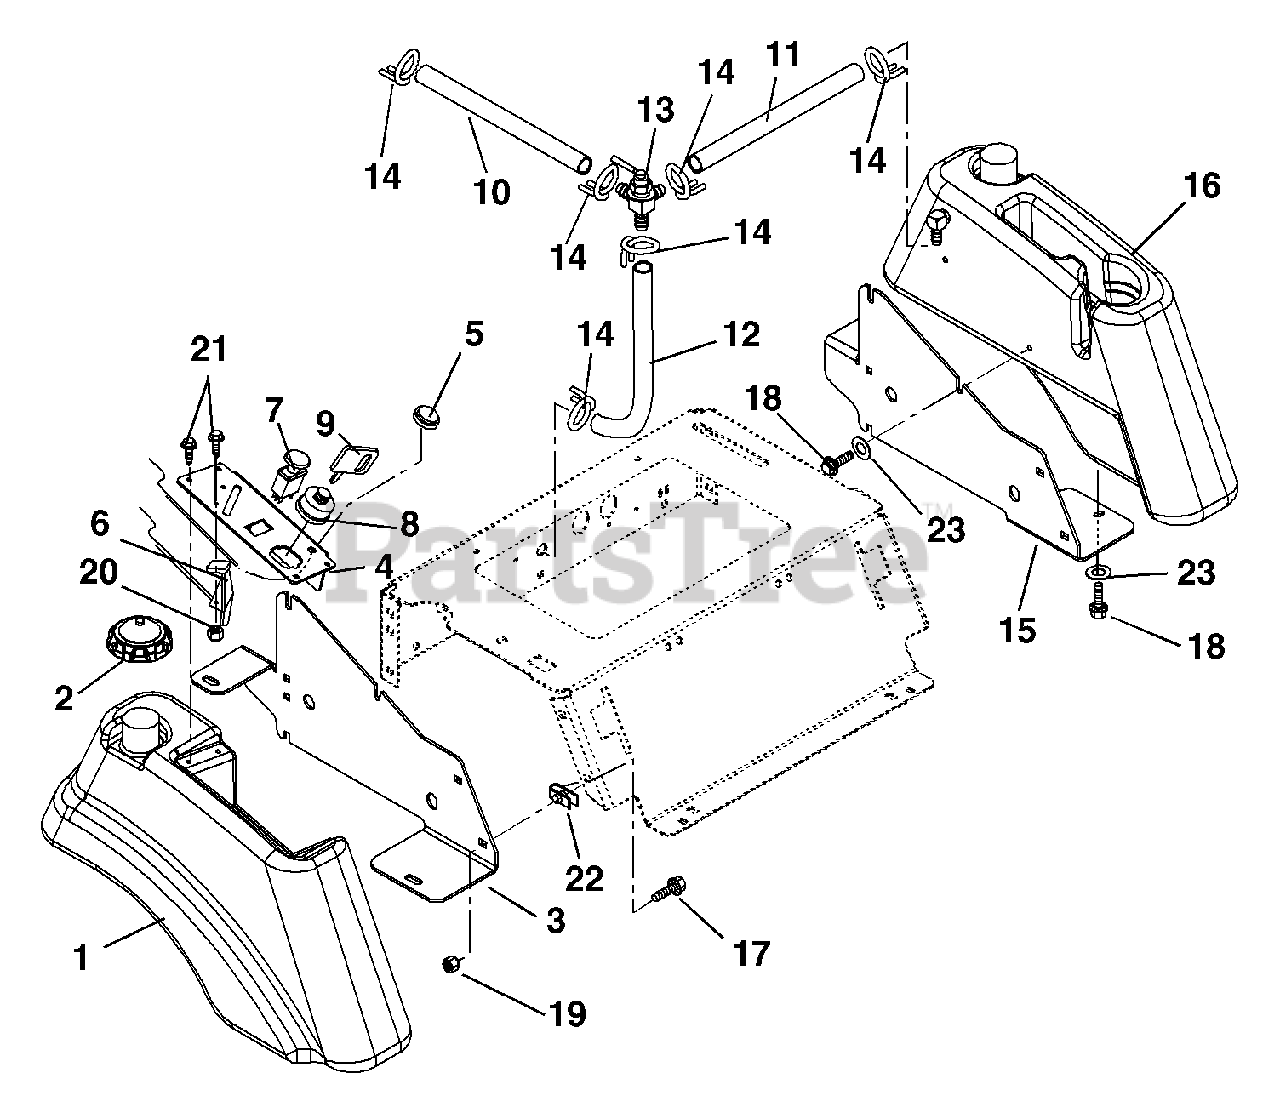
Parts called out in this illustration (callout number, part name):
1	FUEL TANK - RH
2	FUEL CAP
3	SEAT PLATE/TANK SUPPORT RH
4	BKT-CONTROL
5	HOLE PLUG, PLASTIC .44 HOLE
6	THROTTLE CABLE
7	SWITCH, CLUTCH
8	KEY SWITCH
9	KEY -W/CAP
10	GAS LINE-BULK 1/4" I.D.
11	GAS LINE-BULK 1/4" I.D.
12	GAS LINE-BULK 1/4" I.D.
13	VALVE, FUEL
14	CLAMP-HOSE WIRE .490/.510X.116
15	SEAT PLATE LH
16	FUEL TANK - LH
17	@BLT-RDHDSQNK .38-16X1.00 G5YZ
18	BLT-SERHFWH .312-18X.75 YWZC
19	@NUT-LK-NYL-FLG .38-16 YWZC
20	@NUT-LK-NYL 10-24 W/INSRT YWZC
21	@SCR-MCH 10-24X.50 HWH YWZC
22	RETAINER, .38 PUSH-ON
23	WSHR-FL-STL .328X1.0X.094 YWZC
